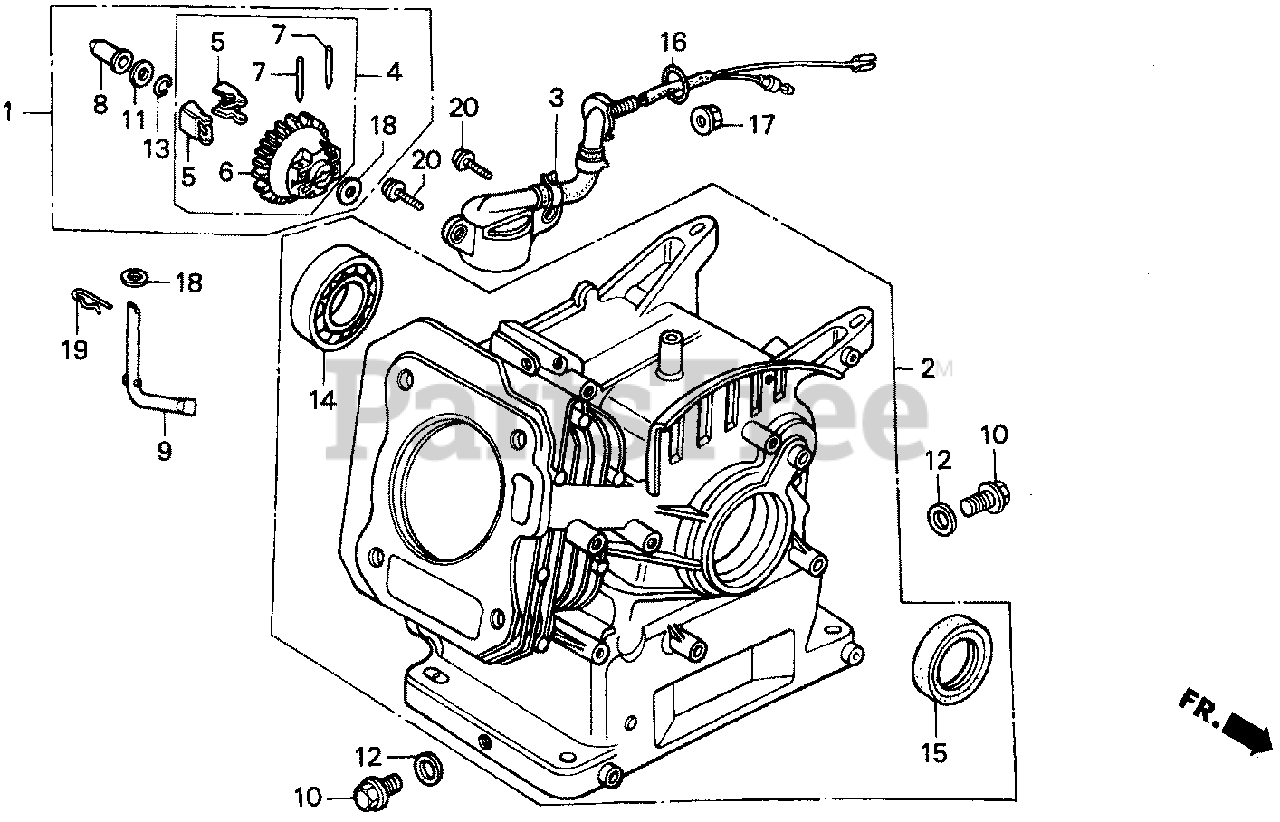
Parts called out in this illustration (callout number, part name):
2	CYLINDER ASSY. (811)
2	CYLINDER ASSY. (OIL ALERT)
3	SWITCH ASSY., OIL LEVEL
4	GOVERNOR ASSY.
5	WEIGHT, GOVERNOR
6	HOLDER, GOVERNOR WEIGHT
8	SLIDER, GOVERNOR
9	SHAFT, GOVERNOR ARM
10	BOLT, DRAIN PLUG
11	WASHER, THRUST (6MM)
12	WASHER, DRAIN PLUG (10.2MM)
13	CLIP, GOVERNOR HOLDER
14	BEARING, RADIAL BALL (6205)
15	OIL SEAL (25X41X6)
16	O-RING (13.5X1.5) (ARAI)
17	NUT, FLANGE (10MM)
18	WASHER, PLAIN (6MM)
19	PIN, LOCK (8MM)
20	BOLT, FLANGE (6X12)
